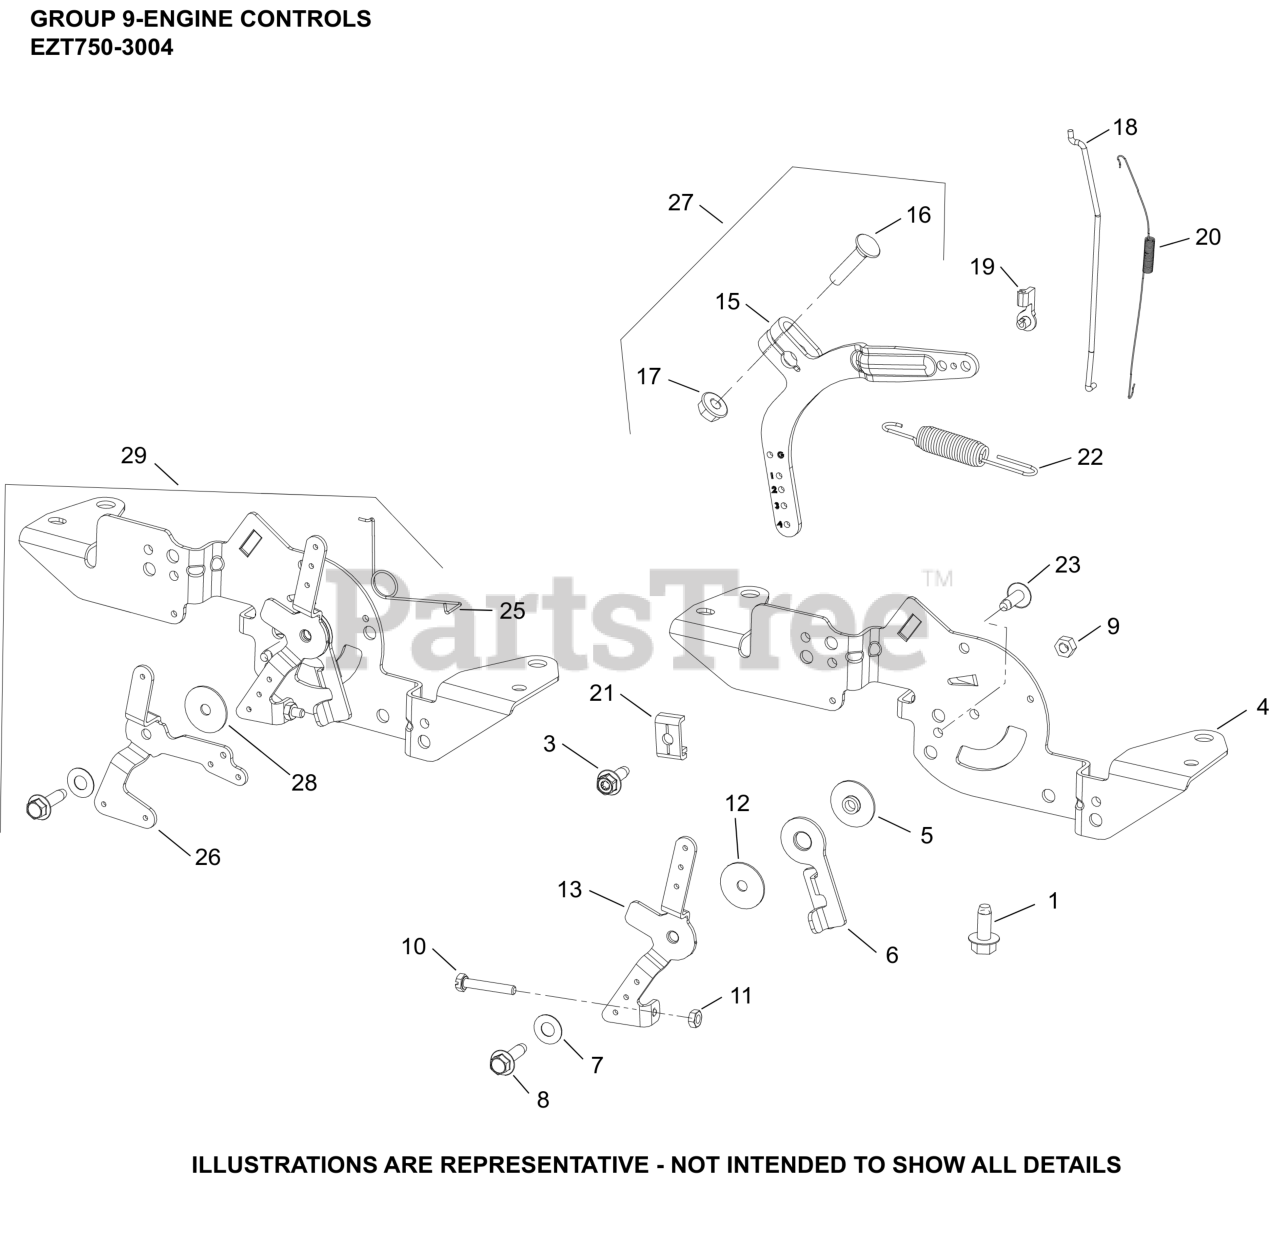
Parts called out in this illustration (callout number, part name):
1	SCREW, THREAD FORMING
3	SCREW, THREAD FORMING
4	BRACKET, SPEED CONTROL
5	SPACER, CONTROL ASSEMBLY
6	LEVER, THROTTLE ACTUATOR
7	WASHER, SPRING 1/4"
8	SCREW, THD FRM-USE 25 086 473-S
9	NUT, LOCK M5X.8
10	SCREW, SLT HD CAP M4X0.7X25
11	NUT, M4X0.7
12	WASHER, FLAT 5 MM
13	LEVER, THROTTLE CONTROL
15	LEVER, GOVERNOR - (#2409069S)
16	BOLT, RD HD SQ NECK M6X1.0X25
17	NUT, FLG M6X1.0
18	LINKAGE, THROTTLE
19	BUSHING, THROTTLE LINKAGE
20	SPRING, LINKAGE
21	CLAMP, CABLE CABLE
22	SPRING, GOVERNOR (CLEAR)
23	SCREW, THREAD FORMING
25	SPRING, CHOKE RETURN
26	LEVER, CHOKE
27	LEVER, GOVERNOR ASSEMBLY
28	WASHER, FLAT 5.5 MM
29	CONTROL ASSEMBLY, DUAL WIRE
